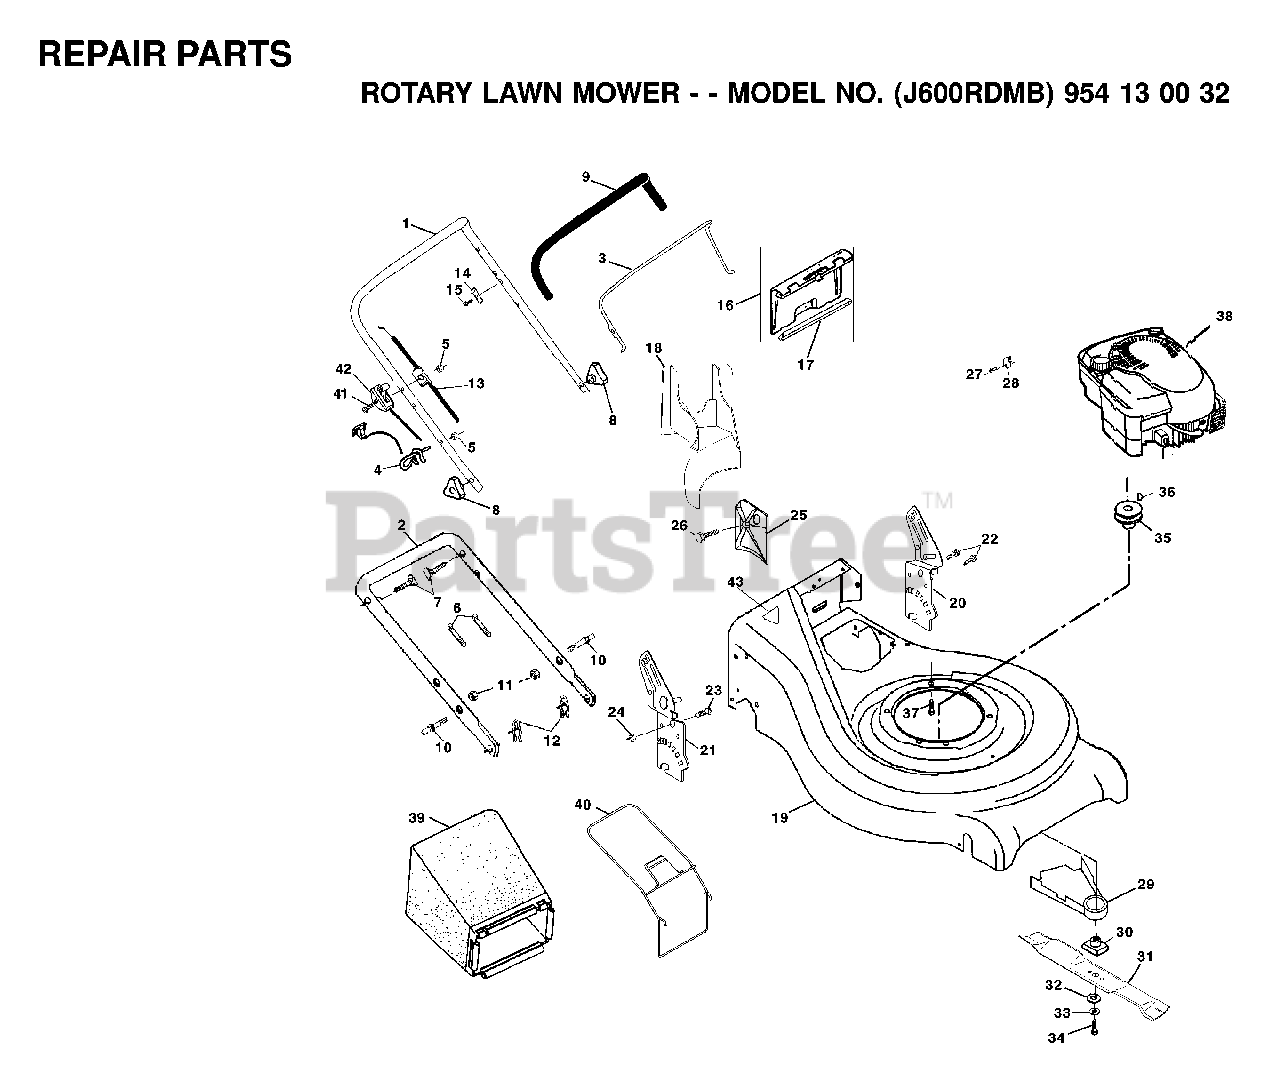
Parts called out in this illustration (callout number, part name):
2	HANDLE
3	CONTROL BAR
4	ROPE GUIDE
5	NUT
6	TIE GUIDE
7	HANDLE BOLT
9	GRIP.HANDLE.FOAM
10	BOLT
11	NUT
12	HAIRPIN COTTER
13	ENGINE ZONE CONTROL
14	BRACKET UPSTOP
15	SCREW.HEX.HEAD.WASHER.10-16
16	REAR DOOR KIT
17	SEALING
18	MULCH PLUG
20	.RACKET
21	BRACKET
22	SELF-TAPPING SCREW 5/16-18X3/4
23	BOLT, HEX HEAD 5/16-18
25	CLIPPING DEFLECTOR
27	SCREW.HEX.HEAD.WASHER.10-16
28	CABLE CLAMP(ENGINE)
29	DEBRIS SHIELD
30	RP BLADE ADAPTOR
32	WASHER,HARDEN
33	LOCKWASHER
34	SCREW, HEX HD 3/8-24 X 1-3/8
35	PULLEY
36	HI PRO KEY PM
37	BOLT 3/8-16X1-1/8
40	GRASS CATCHER FRAME
41	SCREW 1/4-20 X 2.12
42	THROTTLE TRIGGER
43	DECAL MOWER CUT/FINGER
